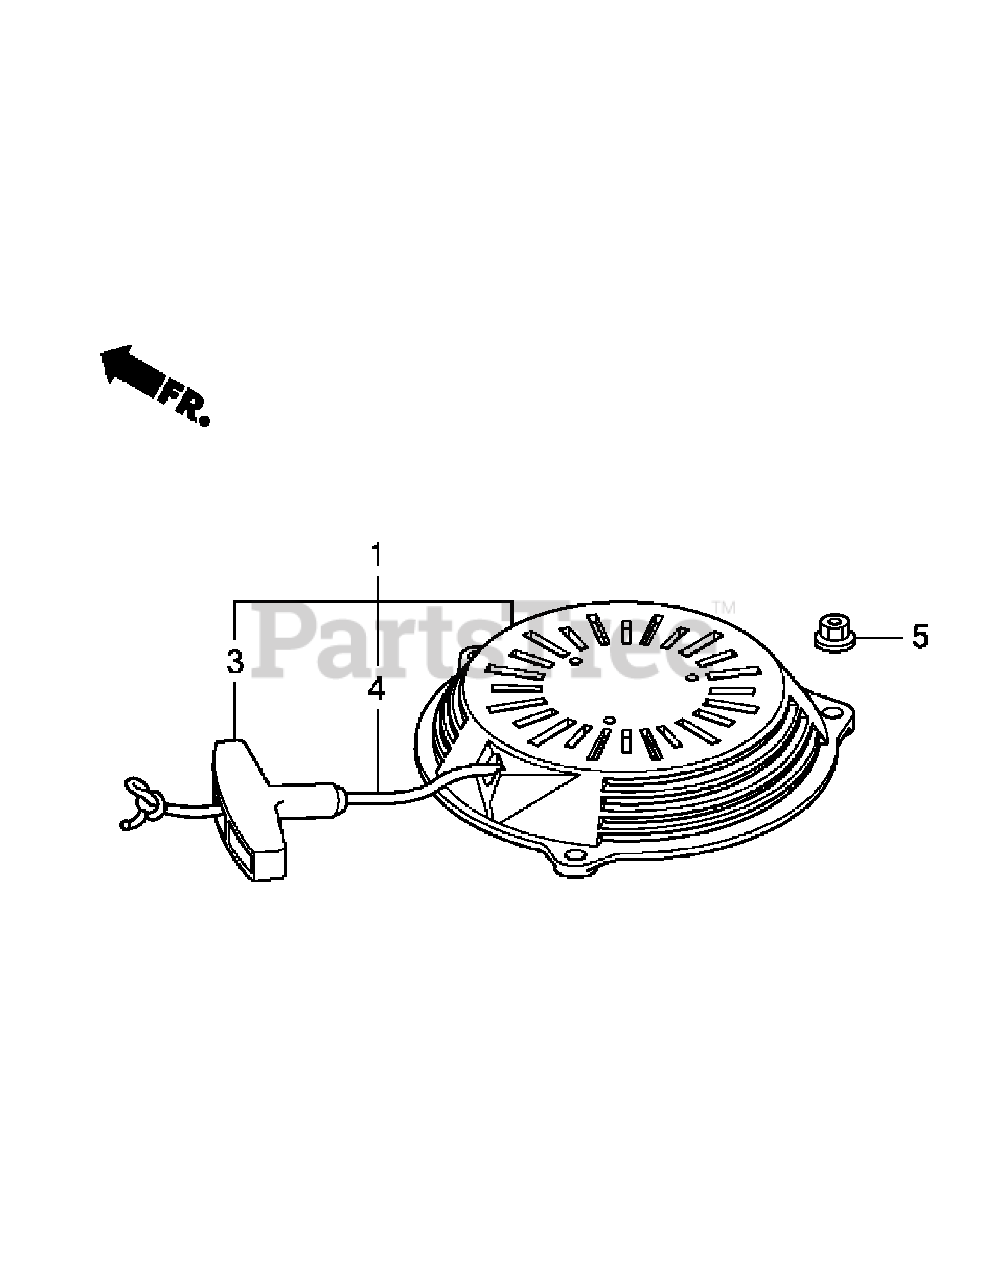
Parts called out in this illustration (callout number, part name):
1	Recoil Starter Assembly
3	Starter Grip
4	Recoil Starter Rope
5	Flange Nut, 6mm
